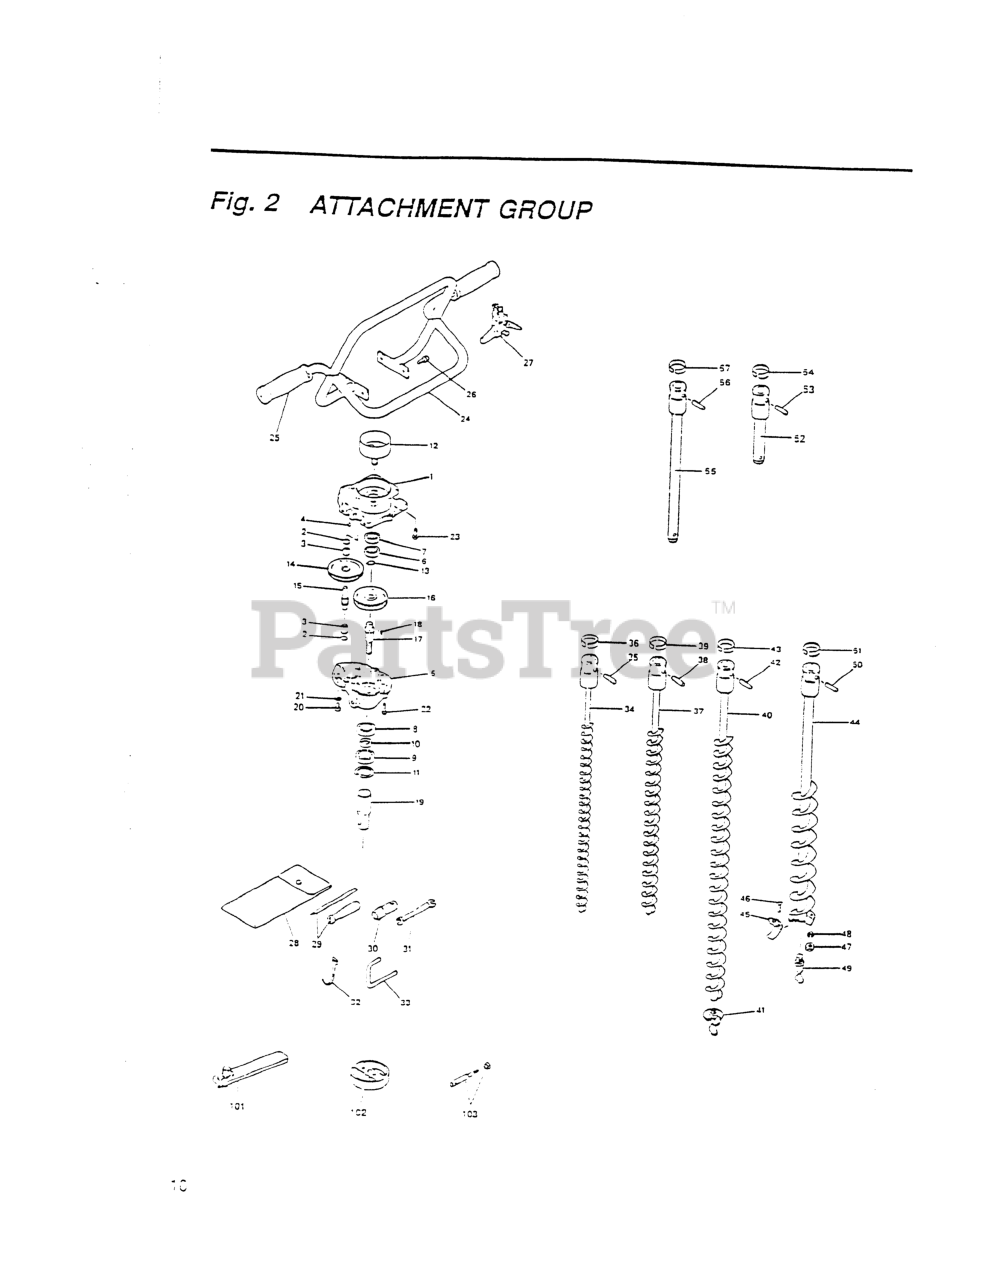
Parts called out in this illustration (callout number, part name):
4	PIN, DOWEL
5	CASE (USE -11201)
6	BEARING
11	RING, SNAP, M35 X 1.5
12	DRUM, CLUTCH
13	RING, SNAP (RPLS 3130-13270)
17	SHAFT, PTO
18	KEY
19	SHAFT
20	BOLT, M6 x 10
21	WASHER, M6 X .8
22	SCREW, M5 X 20
23	BOLT, M6 x 16
25	GRIP (USE -14221)
26	BOLT, M6 x 16
27	LEVER, THROTTLE
29	SCREWDRIVER
30	SOCKET, HEX, 3/4
31	SPANNER, 8 X 10 (RPLS 2540- )
32	BAND
33	PIN
34	DRILL S20 ASS
35	PIN
36	CLIP
37	DRILL S30 ASS
38	PIN
39	CLIP
40	DRILL S40 ASS
42	PIN
43	CLIP
44	DRILL S60 ASS
46	SCREW, M6 X 20
47	NUT, M6 X 5
48	WASHER, M6 X 15
50	PIN
51	CLIP
52	JOINT L100
53	PIN
54	CLIP
55	JOINT L300
56	PIN
57	CLIP
103	(H) ROD ASSY
